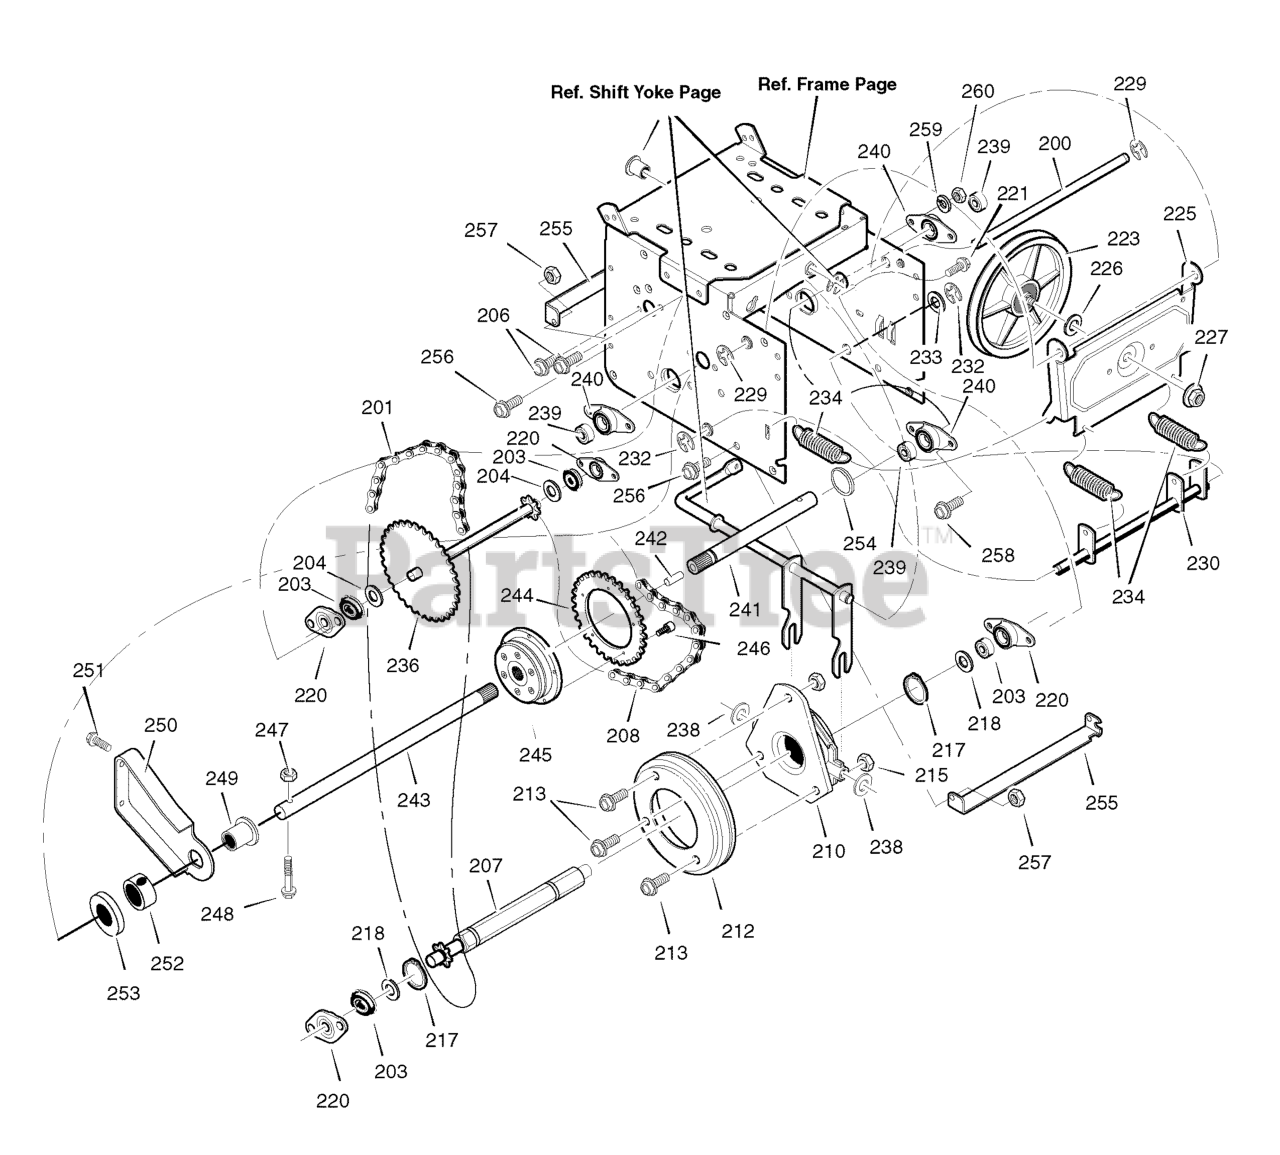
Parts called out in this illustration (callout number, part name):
200	LF AXLE, SWING PLATE YZ
201	CHAIN, ROLLER #420 X 19.00
203	BEARING AND RETAINER, ASSEMBLY
206	SCREW, TAP 5/16-18 X 1/2
207	ASSEMBLY, HEX SHAFT
208	CHAIN, ROLLER #420x18.00 LG
210	BEARING, TRUNION CLUTCH R
212	WHEEL, FRICTION DISC
215	NUT, KEPS HEX 1/4-20
217	RING, RETEXT
220	BEARING AND RETAINER, ASSEMBLY
221	SCREW, TAP 5/16-18 X .5
223	FRICTION PULLY
225	LF PLATE, SWINGING YZ
226	SPACER, FRICTION PULLEY
227	NUT, FLANGE LOCK 3/8-24
229	RETAINER, RING
230	ASSEMBLY, SPRING LINK STEERABLE
232	RETAINER, RING
234	SPRING, EXTENSION
236	SPROCKET SET 33T/7
238	WASHER, FLAT
239	BEARING, BALL
240	RETAINER, BEARING
241	AXLE, LEFT
242	PIN, AXLE
243	AXLE AND BUSHING, RIGHT
244	SPROCKET
245	CLUTCH, AUTO LOCK
247	NUT
249	BEARING, AXLE
250	BRACKET, AXLE SUPPORT
251	SCREW
252	COLLAR, LOCKING
254	RING, SNAP
255	BRACKET, SUPPORT
257	NUT
258	BOLT
259	WASHER
260	NUT
